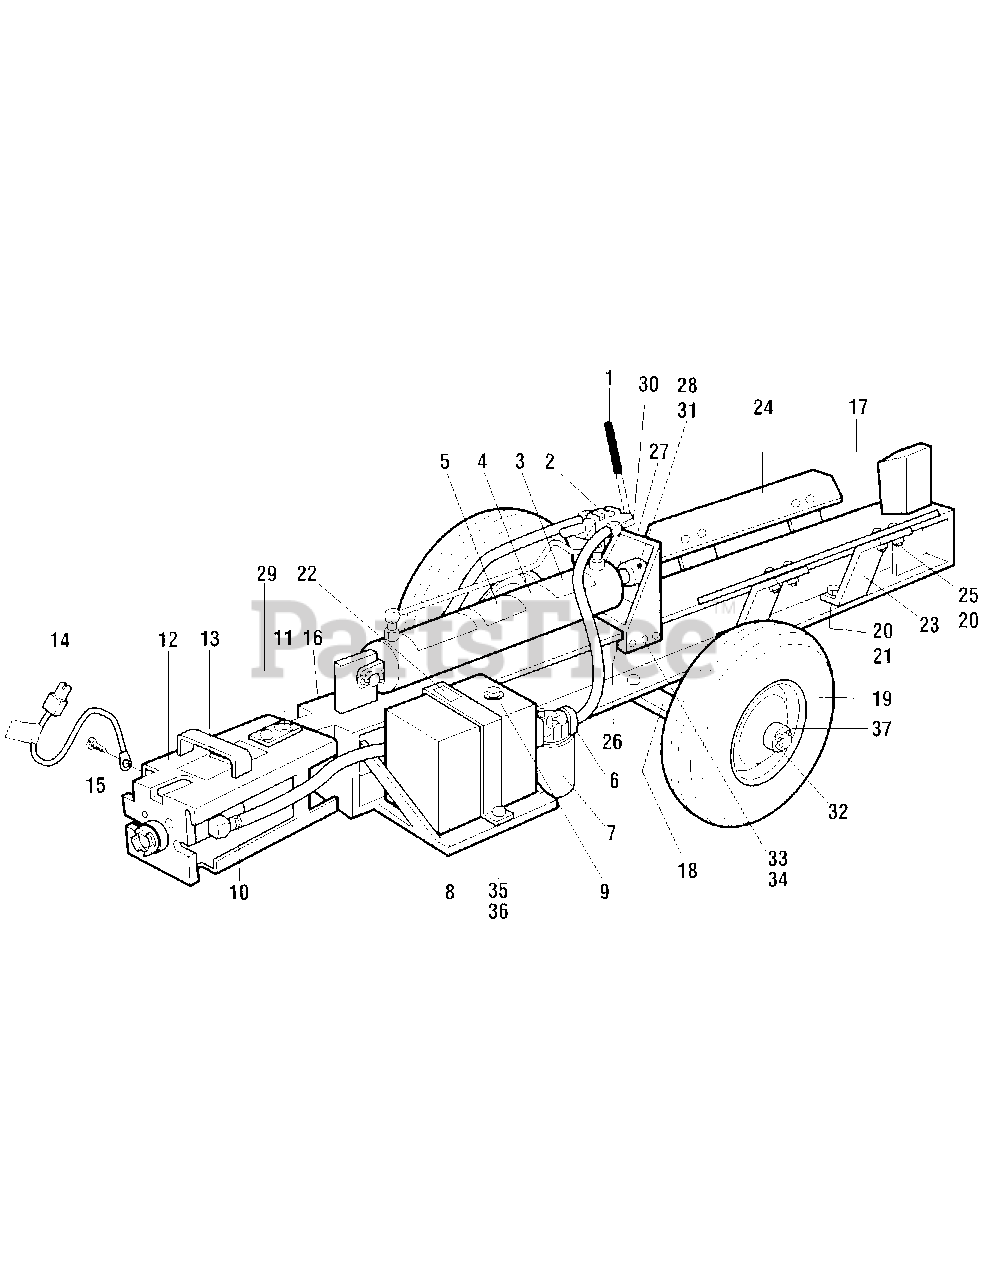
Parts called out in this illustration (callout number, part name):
1	Valve Handle
2	Valve
3	Label In/Out Valve
4	Cylinder 3-1/2" TMC
5	Decal Caution 5"x 10"
6	Filter Housing
7	Filter Element
8	Plastic Tank
9	Plastic Plug 3/4" P68B
10	Hose Clamp # 12
11	Hitch Pivot Pin
12	Swivel Hitch Weldment
13	Decal Caution
14	Forward Interlock Wire
15	Screw # 10-24 x 1"
16	Serial Number Label
17	Rail Weldment
18	Axle Weldment
19	Tire Assembly 480/400 x 8
20	Lock Nut 3/8" - 16
21	HH Bolt 3/8" - 16 x 1-1/4"
22	Decal/Hydraulic Fluid
23	Log Cradle Mount Brkt
24	Log Cradle Bar
25	Carriage Bolt 3/8" -16s 1-1/4"
26	Slide Angle 1.5 x 1.5x5
27	Slide Weldment
28	Slide Pin
29	5/16"-18 x 1" HH Bolt
30	Connecting Link
31	Hair Pin Clip
32	Cotter Key
33	HH Bolt 3/8"-16 x 1-1/4"
34	Hex Nut 3/8"-16
35	HH Bolt 1/4"-20 x 1"
36	Hex Nut 1/4"-20
37	Thrust Washer
